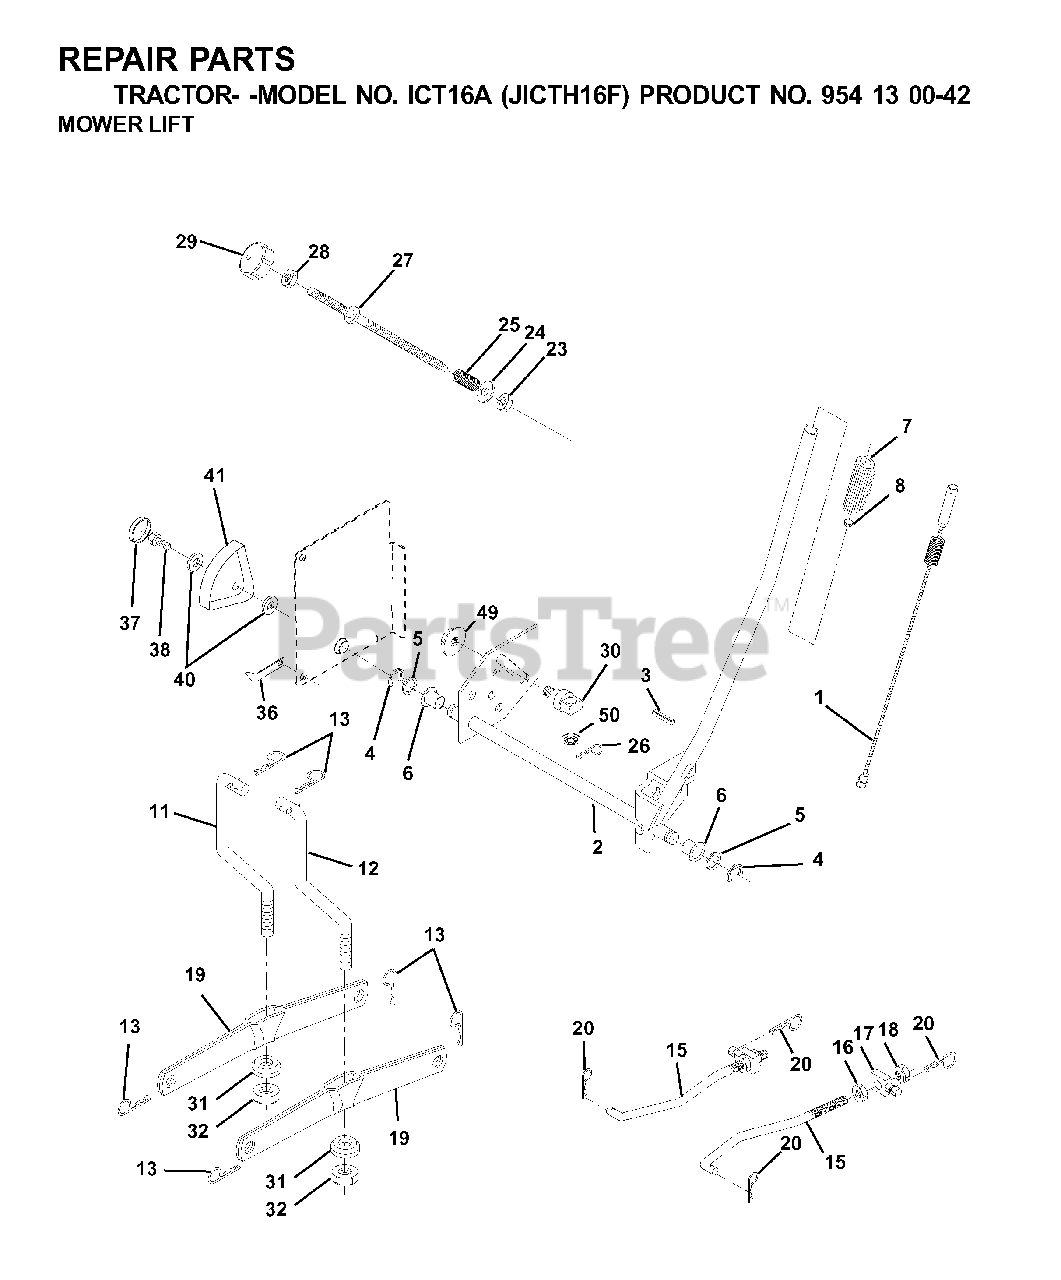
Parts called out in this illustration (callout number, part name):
1	WIRE ASM INNER W/ PLUNGER LT
2	SHAFT ASM R HANDLE
3	PIN GROOVE
4	RETAINING RING LT
6	BEARING.NYLON
7	GRIP HANDLE
8	PLUNGER BUT KIT
11	LINK
12	LINK
13	RETAINER-SPRNG RB
15	LINK.SUSPENSION.FRONT
16	NUT
17	TRUNION
18	NUT
19	ARM.REAR.SUSPENSION
20	SPRING RETAINER
25	SPRING**
26	RETAINER CLIP
27	ROD ADJ LIFT
28	NUT
29	KNOB INF 3/8-16
31	BEARING.PIVOT.LIFT
32	NUT CROWNLOCK 3/8-24
36	POINTER, HEIGHT INDICATOR
37	PLUG,HOLE
38	SCREW 5/16-18X1
41	HEIGHT INDICATOR
49	NUT
50	NUT PUSH M
